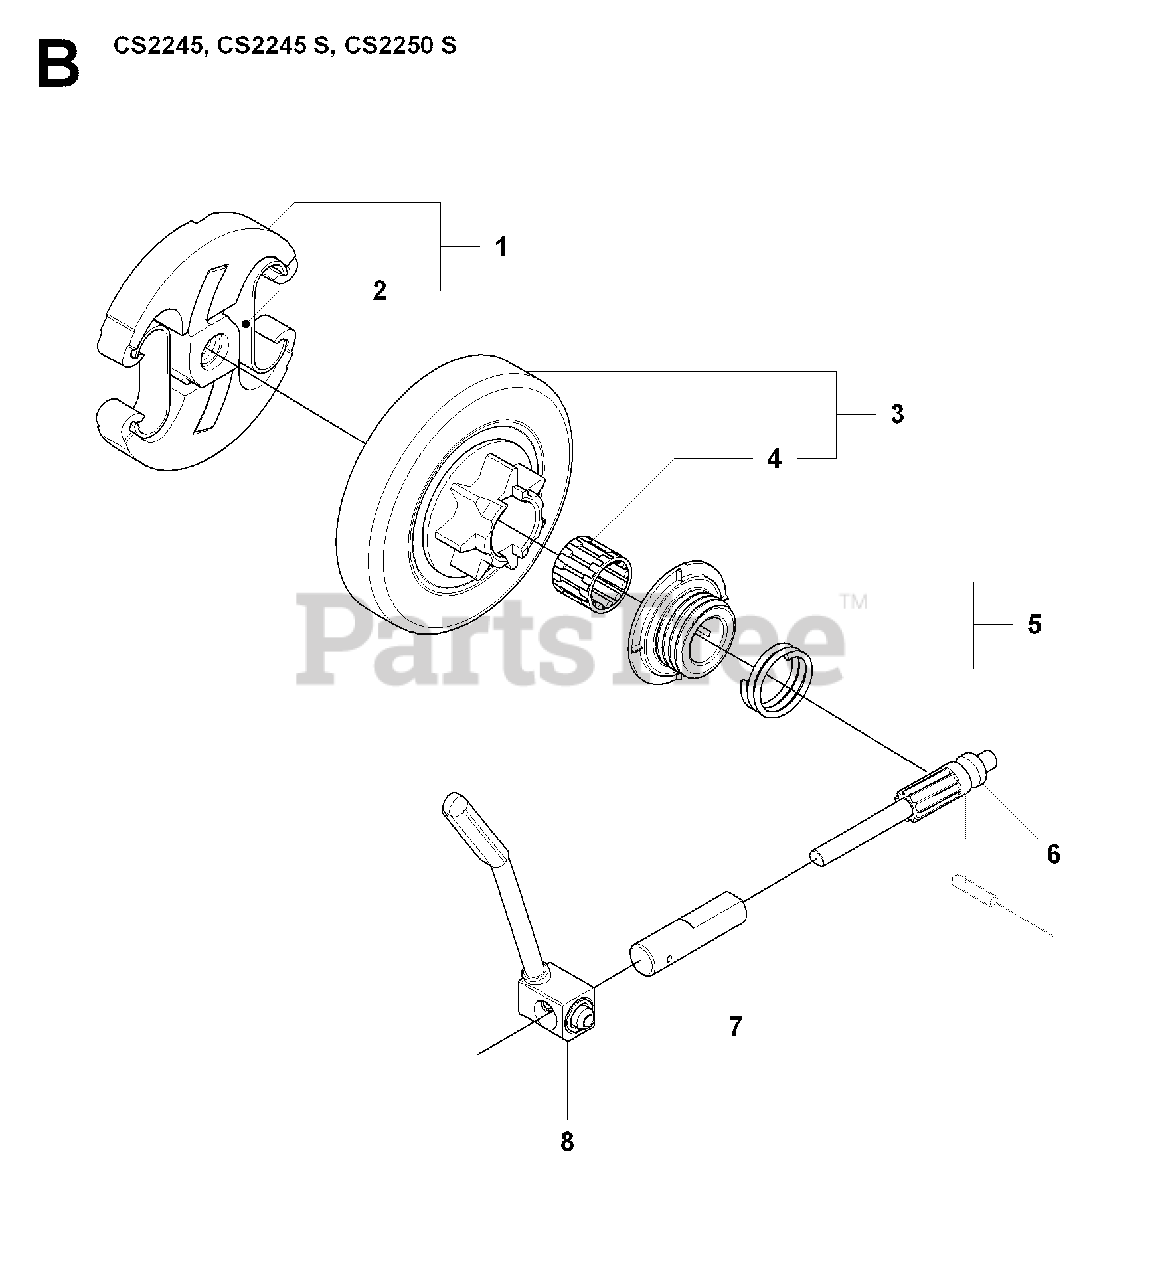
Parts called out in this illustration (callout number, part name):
3	CLUTCH DRUM
4	NEEDLE BEARING
6	%PUMP PISTON
7	PUMP CYLINDER
8	OIL HOSE
